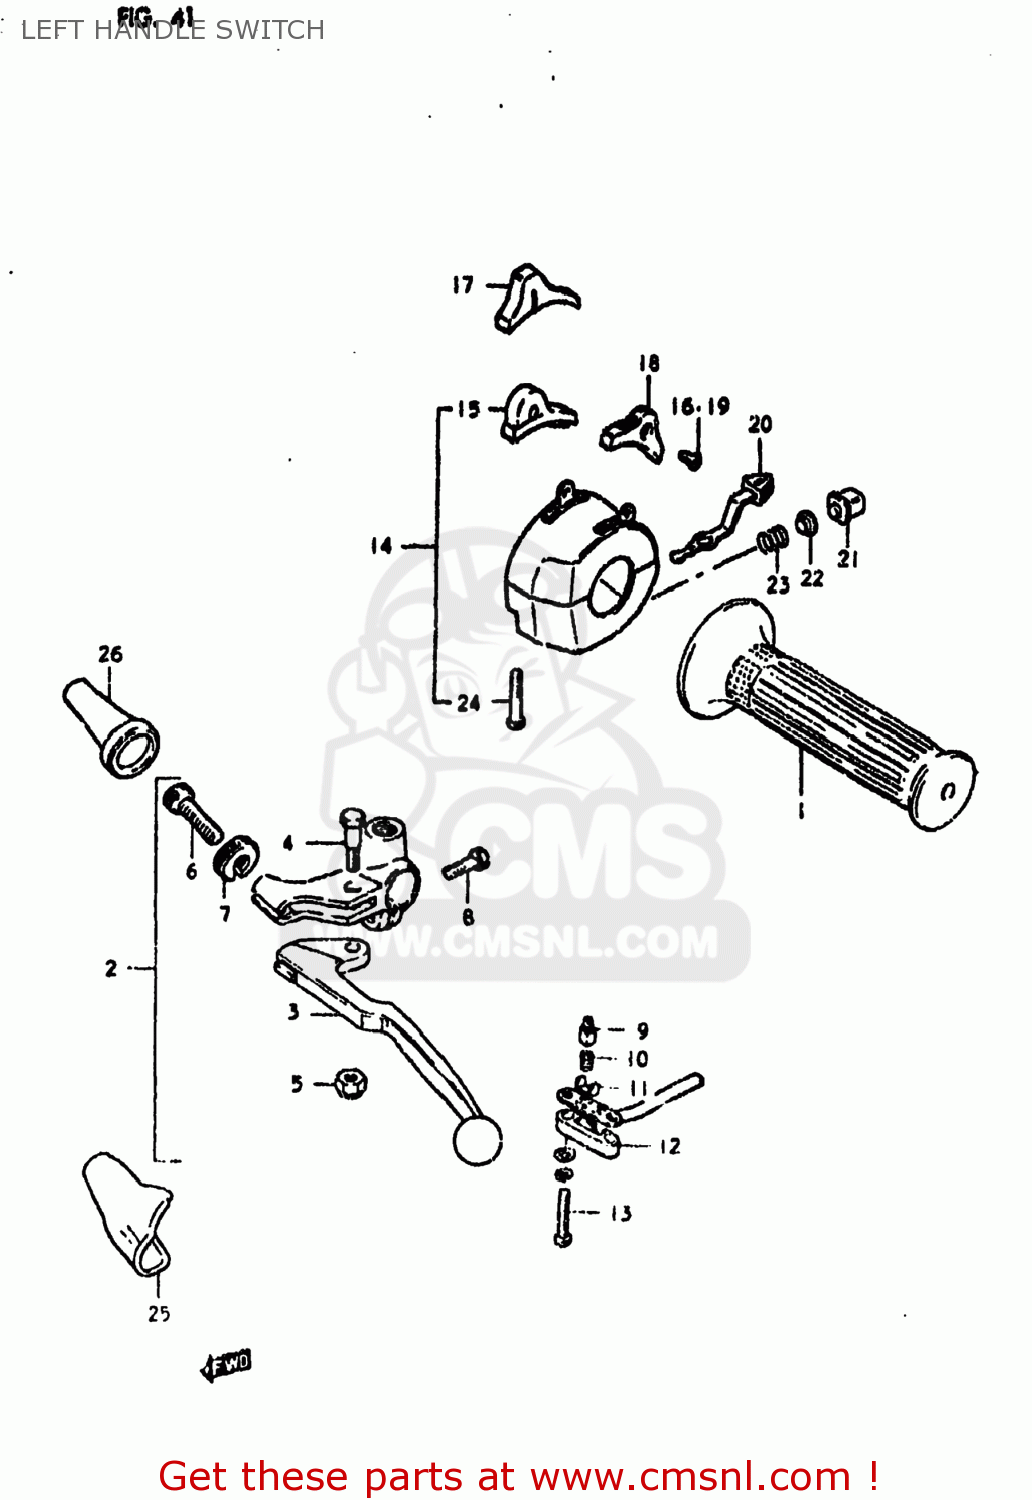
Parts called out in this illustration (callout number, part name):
1	GRIP,LEFT
2	LEVER ASSEMBLY
3	LEVER,CLUTCH
4	BOLT,LEVER
5	NUT 6MM
6	ADJUSTER,CABLE
7	NUT,CABLE ADJUSTER
8	BOLT,CLUTCH LEVER HOLDER
9	HOLDER
10	SPRING
11	PLATE
12	COVER,FR BK TERMINAL BASE
13	SCREW
14	SWITCH ASSY,HANDLE,L
15	KNOB,STOP
16	SCREW
17	KNOB,LIGHTING SWITCH
18	KNOB,DIMMER SWITCH
19	SCREW
20	KNOB,TURNSIGNAL
21	BUTTON,HORN
22	CONTACT
23	SPRING
24	SCREW
25	COVER,CLUTCH LEVER
26	BOOT,CLUTCH CABLE
